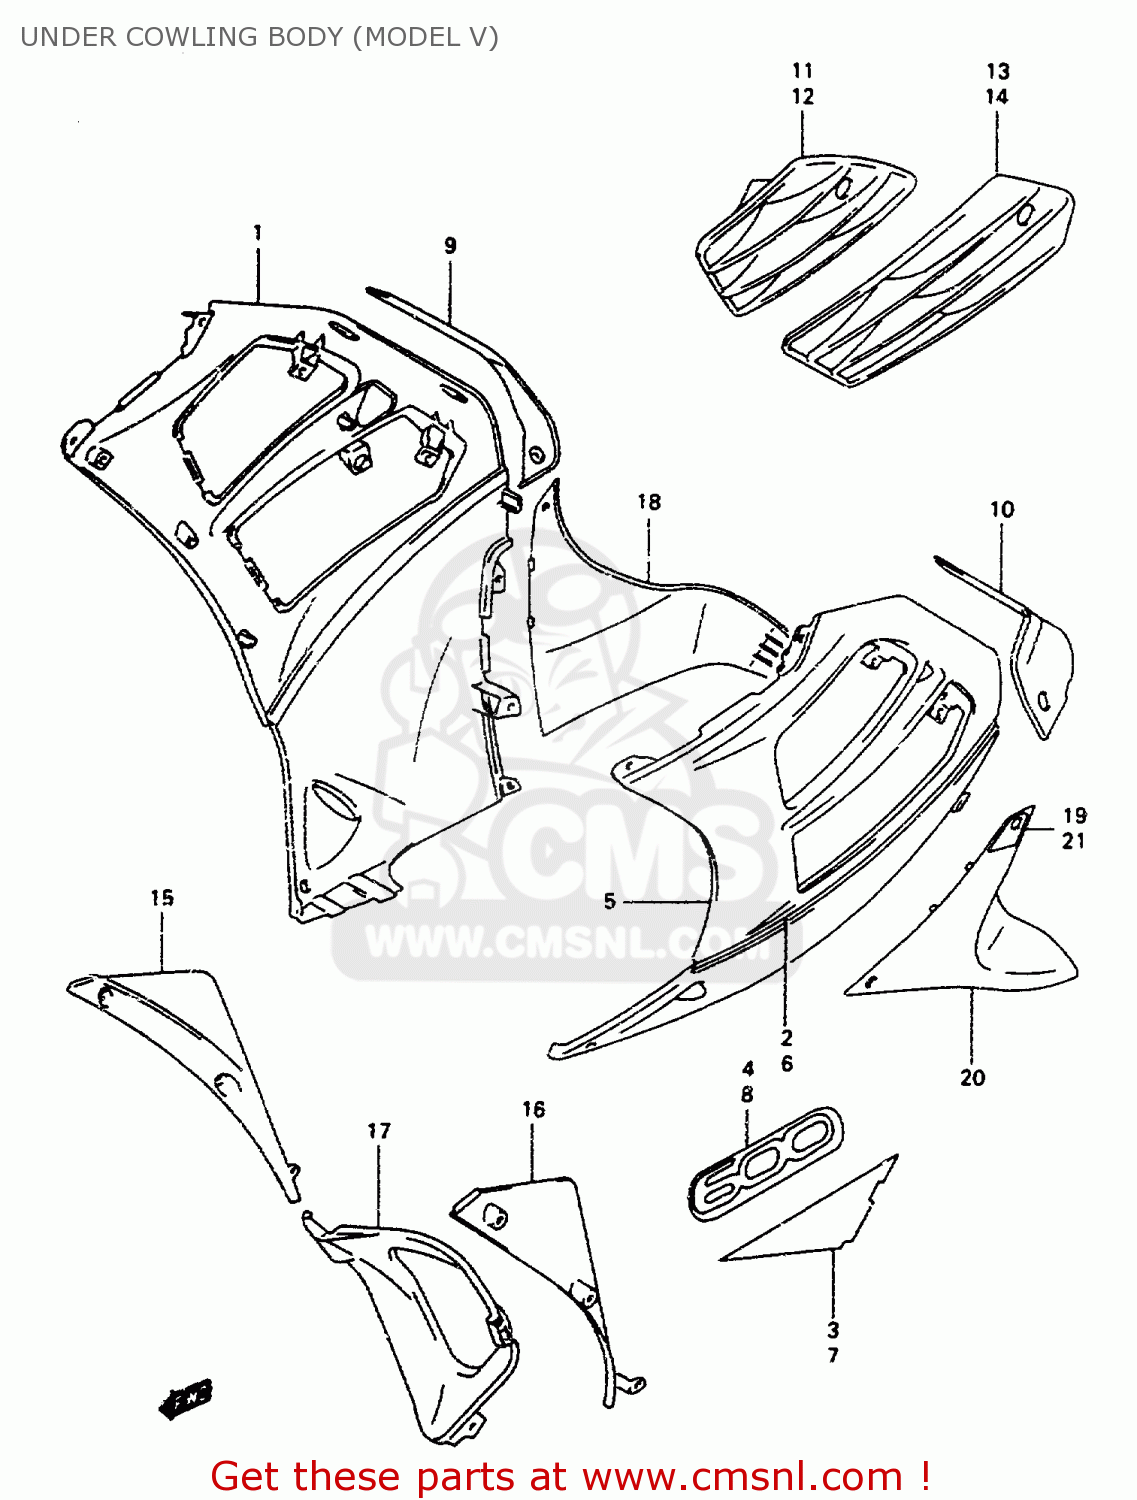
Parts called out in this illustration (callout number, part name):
1	COWLING ASSY,UNDER,R
2	TAPE,UNDER COWL,R
3	TAPE,COWL UNDER LWR,R
4	EMBLEM,COWLING UNDER
5	COWLING,UNDER LH (RED)
6	TAPE,UNDER COWL,L(BLACK)
7	TAPE,COWL UNDER LWR,L
8	EMBLEM,COWLING UNDER
9	PANEL,UNDER,R
10	PANEL,UNDER,L
11	COVER,UNDER COWL UPR,R
12	COVERE,UNDER UPPER LH (RED)
13	COVER,UNDER COWL LWR,R(RED)
14	COVER,UNDER COWL LWR,L
15	COWLING,UNDER INNER,R
16	COWLING,UNDER INNER,L
17	COWLING,UNDER CTR
18	COWLING,REAR RH (BLACK)
19	TAPE,UNDER RH (GREEN)
20	COWLING,UNDER RR,L
21	TAPE,COWLING,UNDER,REAR
